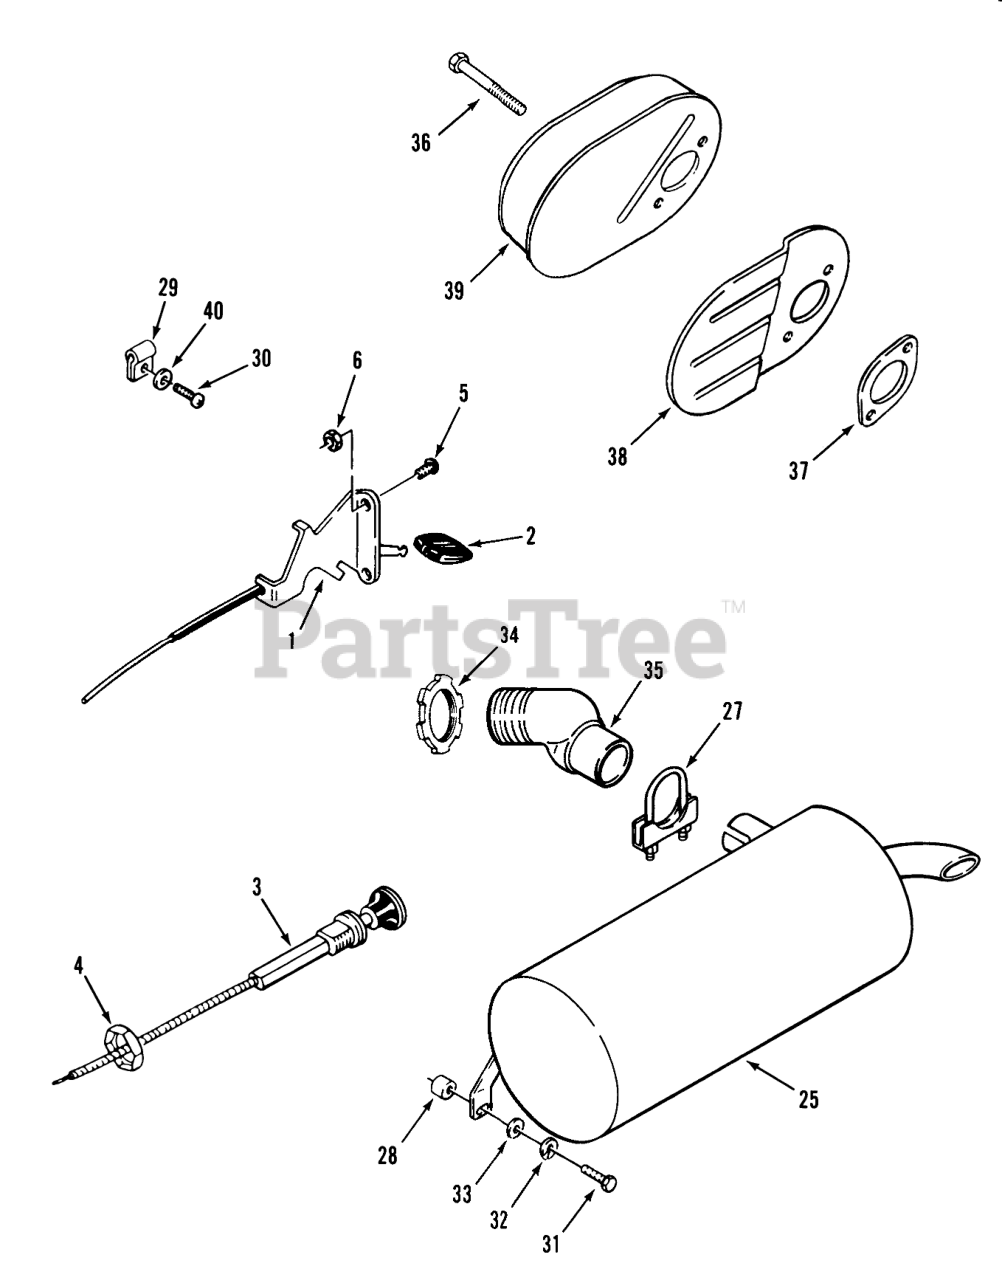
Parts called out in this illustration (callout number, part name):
1	Throttle Control 310, 312, 414
2	KNOB-THROTTLE
3	CONTROL CHOKE
4	NUT-HEX PALNUT
5	SCRW-PHC
6	Nut
25	Muffler
27	CLAMP-1 1/2
28	SPACER
29	CLIP-CABLE
30	Screw, P.H.C.R. #8-32 x2/8
31	Bolt
32	Lockwasher
33	WASHER 5/16 SAE
34	Nut-Lock
35	Elbow
36	Hex Hd. Screw 5/16-18 x 1/2 308
37	Muffler Gasket 308 Only (vendor #41 041 01)
38	Cylinder Baffle
39	Perforated Muffler 308 Only (vendor #41 068 02)
40	Washer
